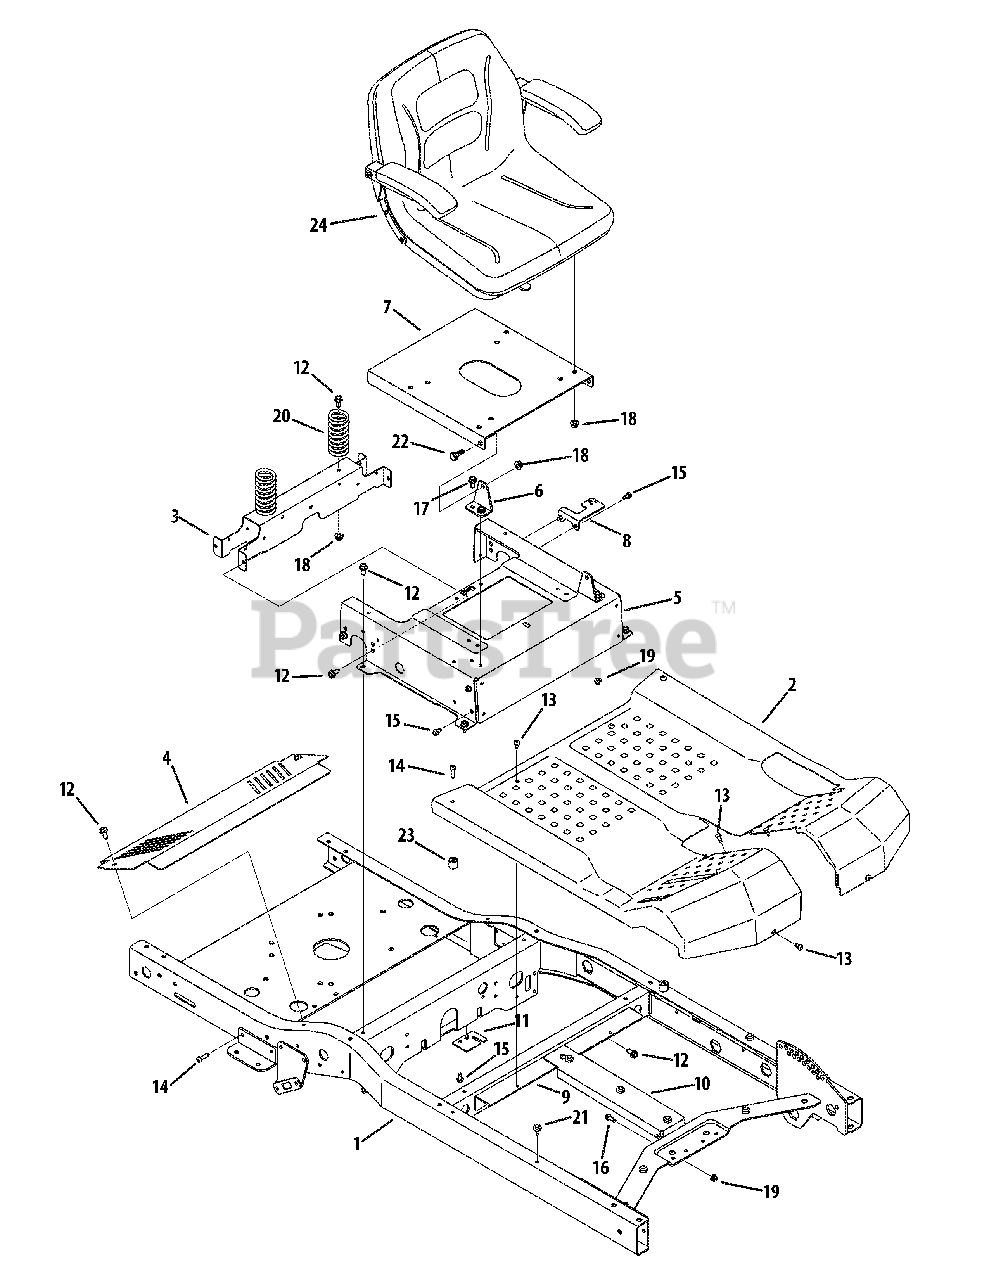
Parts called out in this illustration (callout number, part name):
1	Frame Assembly
4	Transmission Cover
5	Seat Mount Frame
6	Pivot Seat Bracket
7	Seat Base
8	Brake Switch Mount Bracket
9	Running Board Mount Bracket
10	Floor Pan Frame Support
12	Hex Washer Screw, 5.16-18 x .750
13	Screw, 1.4-20 x .5
14	Screw, 1.4-20 x 1.0
15	Screw, 1.4-20 x .500
16	Screw, 1.4-20 x .750
17	Hex Screw, 1.4-20 x .75
18	Flange Lock Nut, 5/16-18
19	Flange Lock Nut, 1.4-20
20	Comp. Spring, 1.71 x 3.735 x .238
21	Bumper, .62 x .3
22	Shoulder Screw, 5.16-18 x .437 x .268
23	Spacer, .281 x .750 x .680
24	Front Cut Seat w/ Arms
